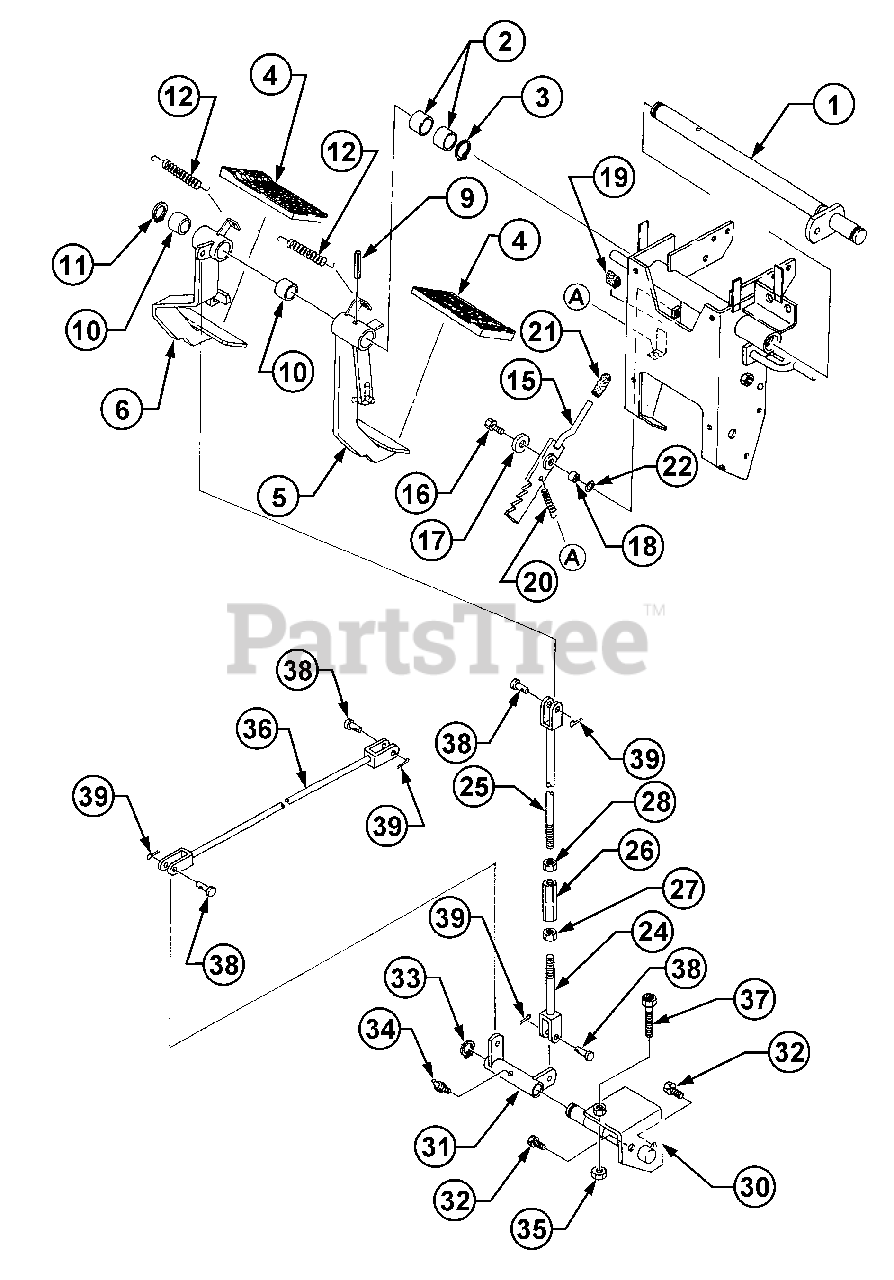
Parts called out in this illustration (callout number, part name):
5	Pedal Brake L.H.
6	Pedal Brake R.H.
15	Lever Parking
16	Bolt, w/Washer
30	Shaft Link R.H.
31	Link Brake R.H.
32	Bolt,w/Washer
34	Nipple, Grease
37	Bolt, Stopper
